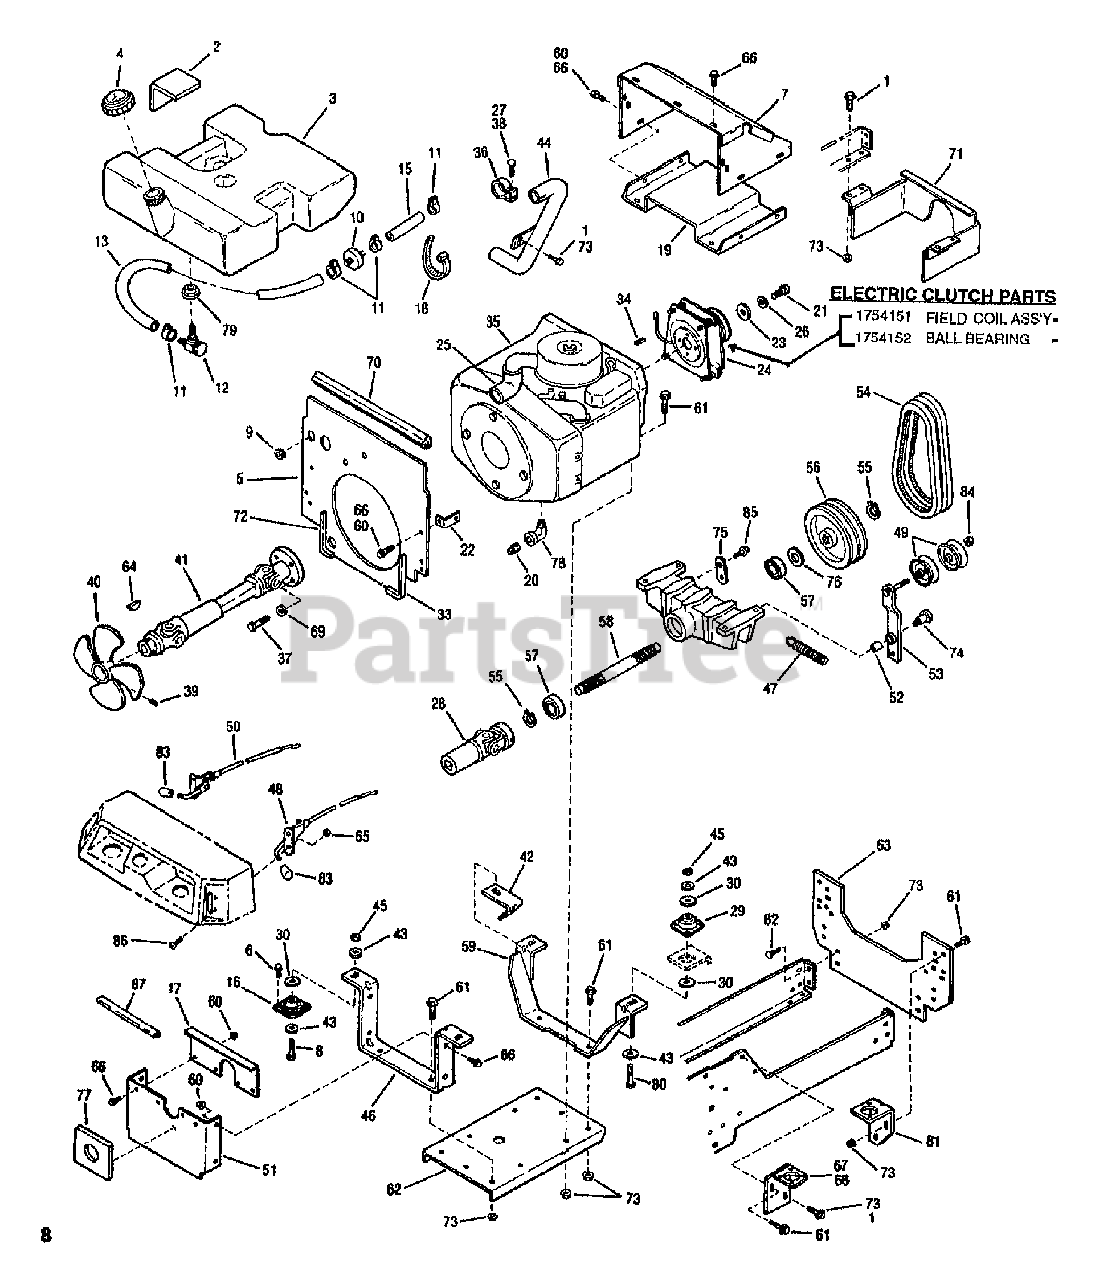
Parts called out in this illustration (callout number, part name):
2	PAD-FUEL TANK
3	ASSM-FUEL TANK
4	CAP-FUEL
5	SHIELD-HEAT
7	ASSM-HEAT SHIELD
8	SCR-HH 3/8-16X2.25 G5 ZP
9	BUSHING
10	FILTER-FUEL
11	CLAMP-HOSE
12	VALVE-SHUT OFF
13	FUEL LINE
15	LINE-FUEL
17	SHIELD-GRASS
18	TIE-CABLE NYLON BLACK
19	SHIELD-HEAT
20	PLUG-PIPE
21	SCR-HH 7/16-20X1.25 G5ZP
22	BRACKET
23	WASHER-1.7X.453X.25
24	ELEC-CLUTCH/BRAKE
25	HOSE-AIR CLEANER
26	WASHER-LK .438 ZP
27	NUT-H/LK 5/16-18
28	ASSM-U JOINT
29	MOUNT
30	WASHER
33	SEAL-RH
35	KOHLER ENGINE 18HP MODEL KT18QS-24599
36	CLAMP
37	SCR-HH 3/8-16X1.0 G5 ZP
38	SCR-CARR 5/16-18X1.25 G2ZP
39	SCR-SQ HD SET 5/16X3/4
40	FAN
41	SHAFT-DRIVE
43	WASHER-FLAT 1.25X.406X.179
44	PIPE-EXHAUST
45	NUT-LOCK 3/8-16
46	SUPPORT-REAR MOUNT
47	SPRING
48	THROTTLE-CONTROL
49	SHEAVE-IDLER
50	CHOKE-CONTROL
51	SHIELD-GRASS
52	BUSHING
53	ASSM-ARM
54	BELT SET
55	RING-HEAVY EXT HD 1.0 ID
57	BEARING-BALL
58	SHAFT-PTO
59	ASSM-SUPPORT
60	NUT-HF/LK 1/4-20 ZP
61	SCR-HFLK 3/8-16X1.00 ZP
62	MOUNT-ENGINE
64	KEY-WOODRUFF
65	NUT W/LKWASHER 10-24 ZP
66	SCR-HFLK 1/4-20X.50 ZP
67	HANGER ASSY.
68	ASSM-HANGER LH
69	WASHER-LK .375 DEPL
71	ASSM-GUARD
72	SEAL-LH
73	NUT-HFLK 3/8-16 ZP
75	ANCHOR-SPRING
76	WASHER-THRUST
78	ELBOW-45 DEGREES
79	BUSHING-RUBBER
80	SCR-HHC 3/8-16X3.25
83	KNOB
84	NUT-HEX/JAM 3/8-16
85	SCR-HFLK 5/16-18X.75 ZP
87	GASKET-HEAT SHIELD
